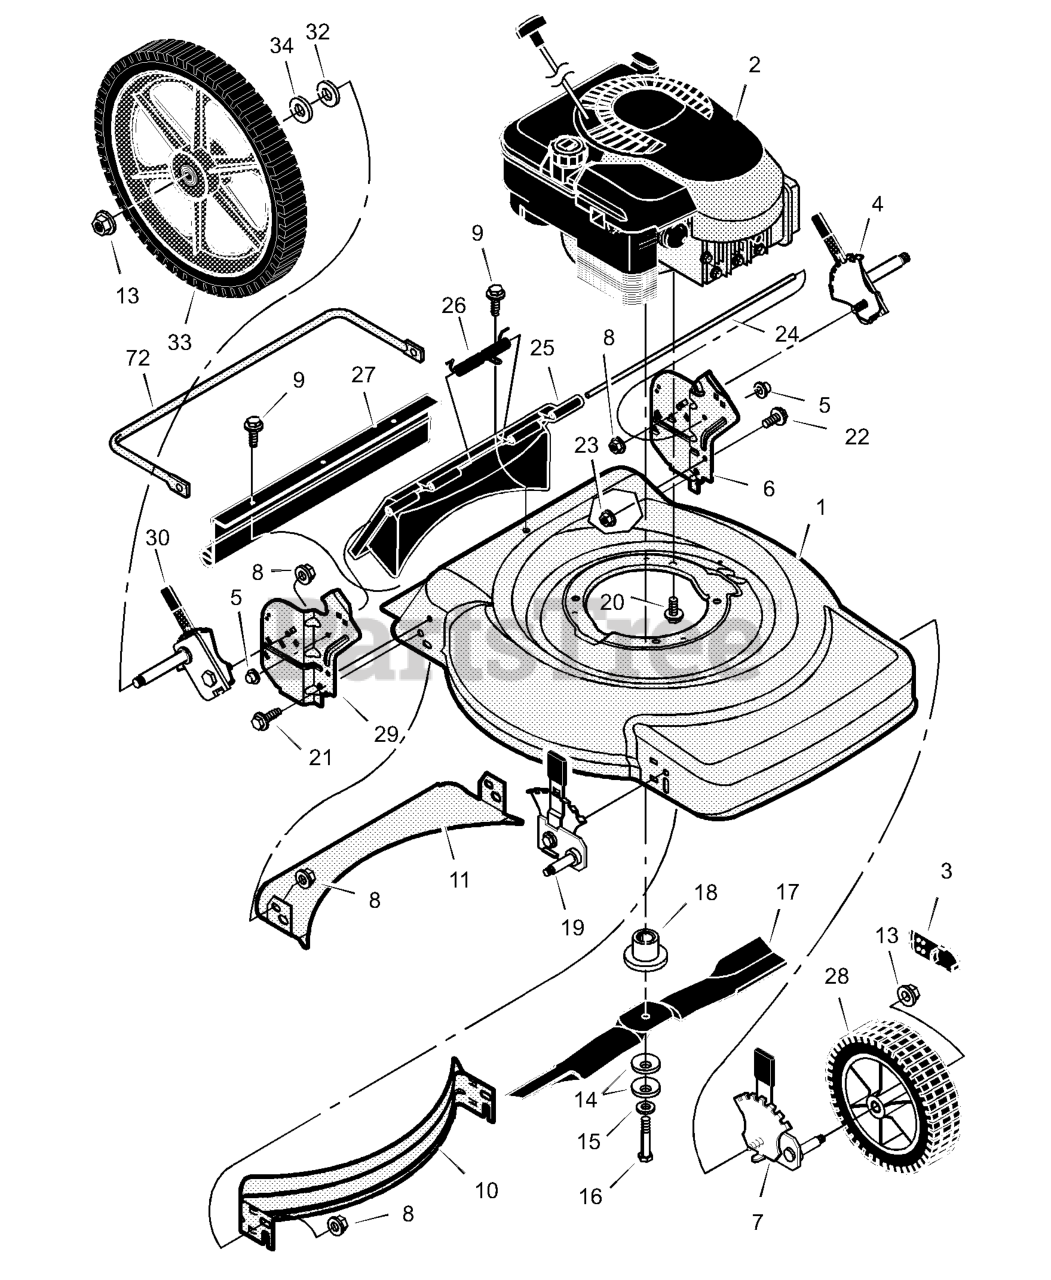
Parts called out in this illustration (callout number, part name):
2	Engine
3	Cap, Hub
4	Adjuster, Left Rear Height
5	Push On Cap
6	Bracket, Left Handle
7	Adjuster, Left Front Height
8	Nut, Flange
10	Baffle, Front
11	Baffle, Rear
13	Nut, Flange
14	Washer, Belleville
18	Adapter, Blade
19	Adjuster, Right Front Height
20	Bolt, Engine
21	Bolt
22	Bolt
23	Nut, Flange
24	Rod, Pivot
25	Door, Rear (Black)
26	Spring
27	Guard, Rear
28	Wheel & Tire, Front
29	Bracket, Right Handle
30	Adjuster, Right Rear Height
33	Wheel & Tire, Rear
